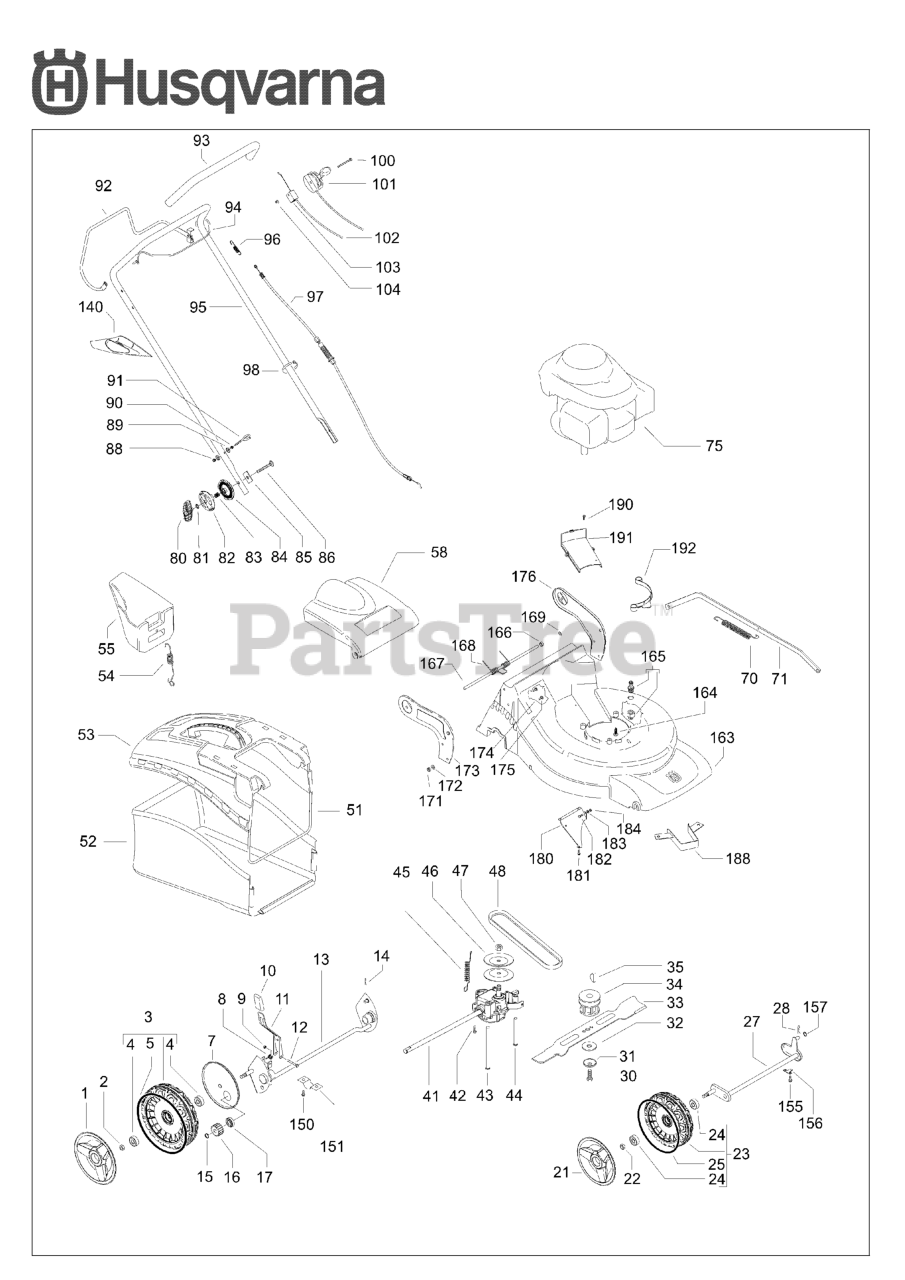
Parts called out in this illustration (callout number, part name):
11	LIFTING LEVER ASSY FOR REAR AX
51	FRAME 51 CAST
53	COVER HARD TOP
58	DEFLECTOR 51 CAST ORANGE
102	BRAKE WIRE
168	SPRING 51 CAST
